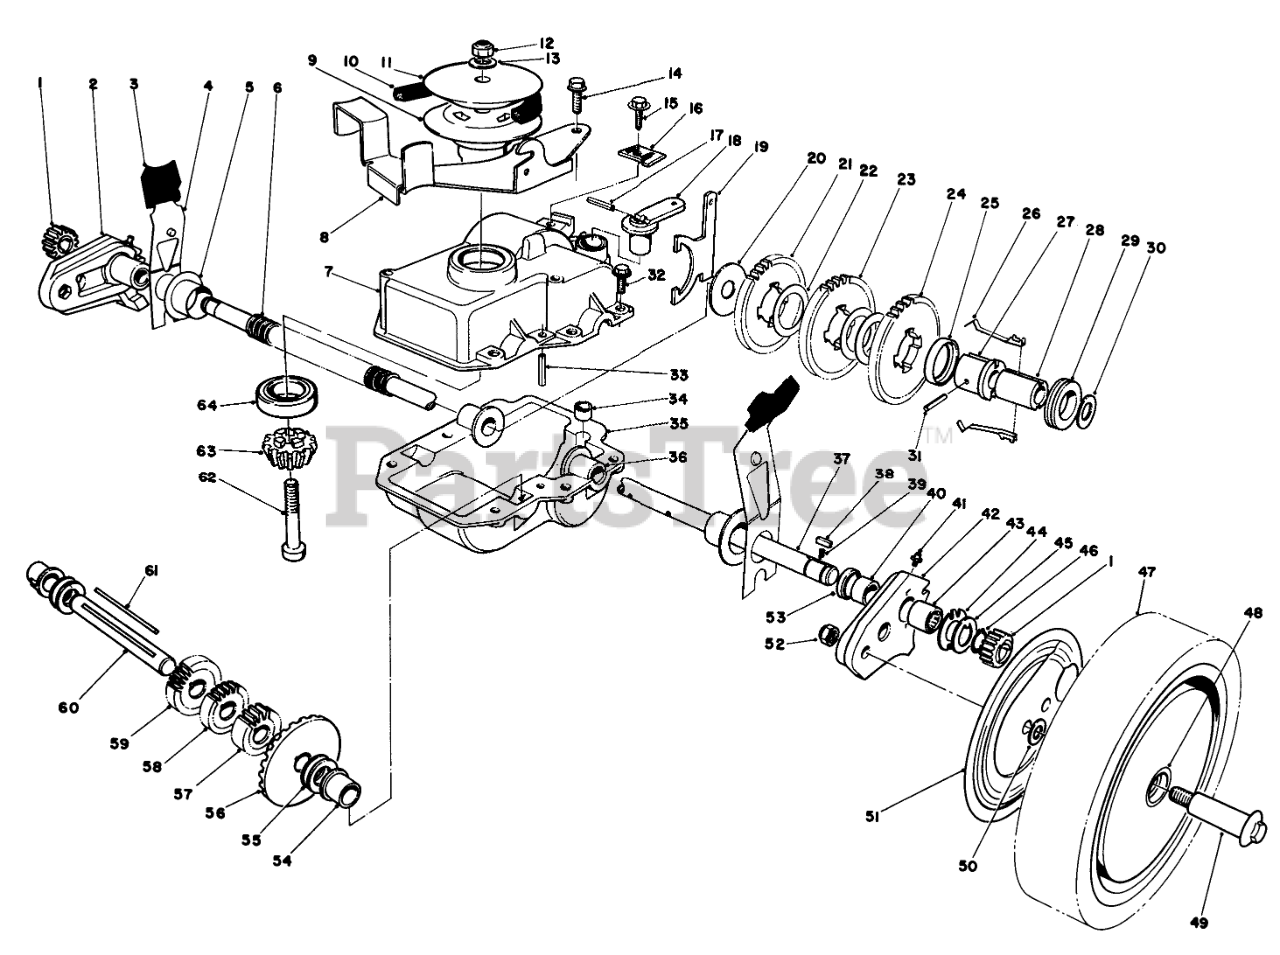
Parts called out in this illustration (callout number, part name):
1	GEAR-PINION
2	Pivot Arm Assembly-R.H. (Incl. Ref. #40, 41, 43 & 53)
3	KNOB-ARM
4	SPRING ARM ASM SP
5	CAP-END
6	CONDUIT-CONVOLUTED, SPLIT
7	Case-Upper
8	BELT GUIDE BRKTB
9	PULLEY-LOWER HALF
10	V-BELT
11	PULLEY-UPPER HALF
12	NUT-LOCK, NI
13	WASHER-FLAT
14	SCREW
15	SCREW-HWHTF
16	Cable Clamp
17	PIN-COIL
18	LEVER-SHIFT
19	Shift Yoke
20	WASHER
21	GEAR-38T
22	WASHER
23	GEAR-42T
25	RETAINER-KEY
26	KEY-SHIFT
27	SLEEVE-GEAR
28	SLEEVE
29	COLLAR-SHIFT
30	WASHER-PLAIN
31	PIN-SPRING
32	SCREW-HWHTF
33	ROLL PIN 3/16 X 1 IN
34	BUSHING-YOKE
35	LOWER GEAR CASE CAST
36	Bushing-Output Shaft
37	Output Shaft
38	KEY RECTANGULAR
39	SPRING-COMPRESSION
40	BUSHING
41	FITTING-GREASE
42	Pivot Arm Assembly-L.H. (Incl. Ref. #40, 41, 43 & 53)
43	BEARING-ROLLER
44	INNER THRUST WASHER
45	WASHER-THRUST, OUTER
46	RING-RETAINING
47	Wheel, Tire & Gear Assembly (Incl. Ref. #48)
48	BUSHING
49	WHEEL BOLT
50	WASHER
51	WHEEL COVER
52	NUT-LOCK
53	SEAL-OIL
54	BUSHING
55	WASHER-THRUST
56	BEVEL GEAR
57	GEAR-12T
58	GEAR-14T
59	GEAR-18T
60	INTERMEDIATE SHAFT
61	Key Square
62	Screw-Socket Hd
63	BEVEL PINION
64	BEARING-BALL
